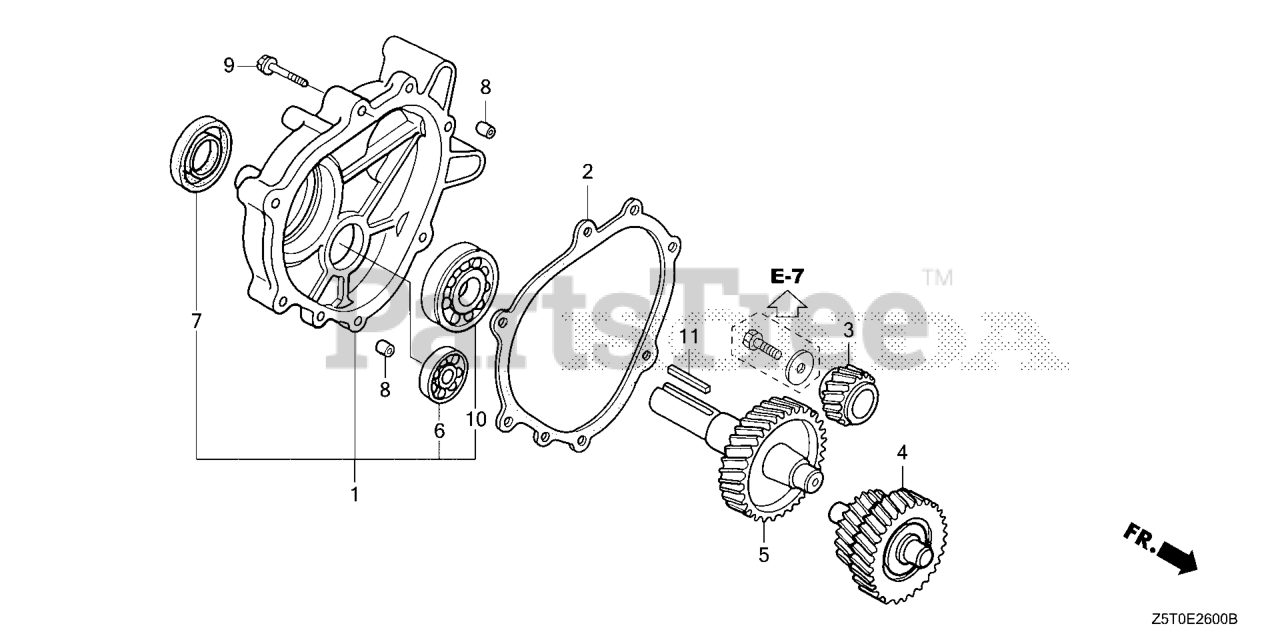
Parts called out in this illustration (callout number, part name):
1	COVER ASSY., GEAR CASE
2	GASKET, CHAIN CASE COVER
3	GEAR, PRIMARY DRIVE
4	COUNTERSHAFT
5	SHAFT, P.T.O. (L-TYPE)
6	BEARING, RADIAL BALL (6202)
7	OIL SEAL (30X46X8) (NOK ASIA)
8	PIN A, DOWEL (8X14)
9	BOLT, FLANGE (8X40) Use up to Engine SN 1003236.
10	BEARING, RADIAL BALL (6206)
11	KEY (7X7X33)
